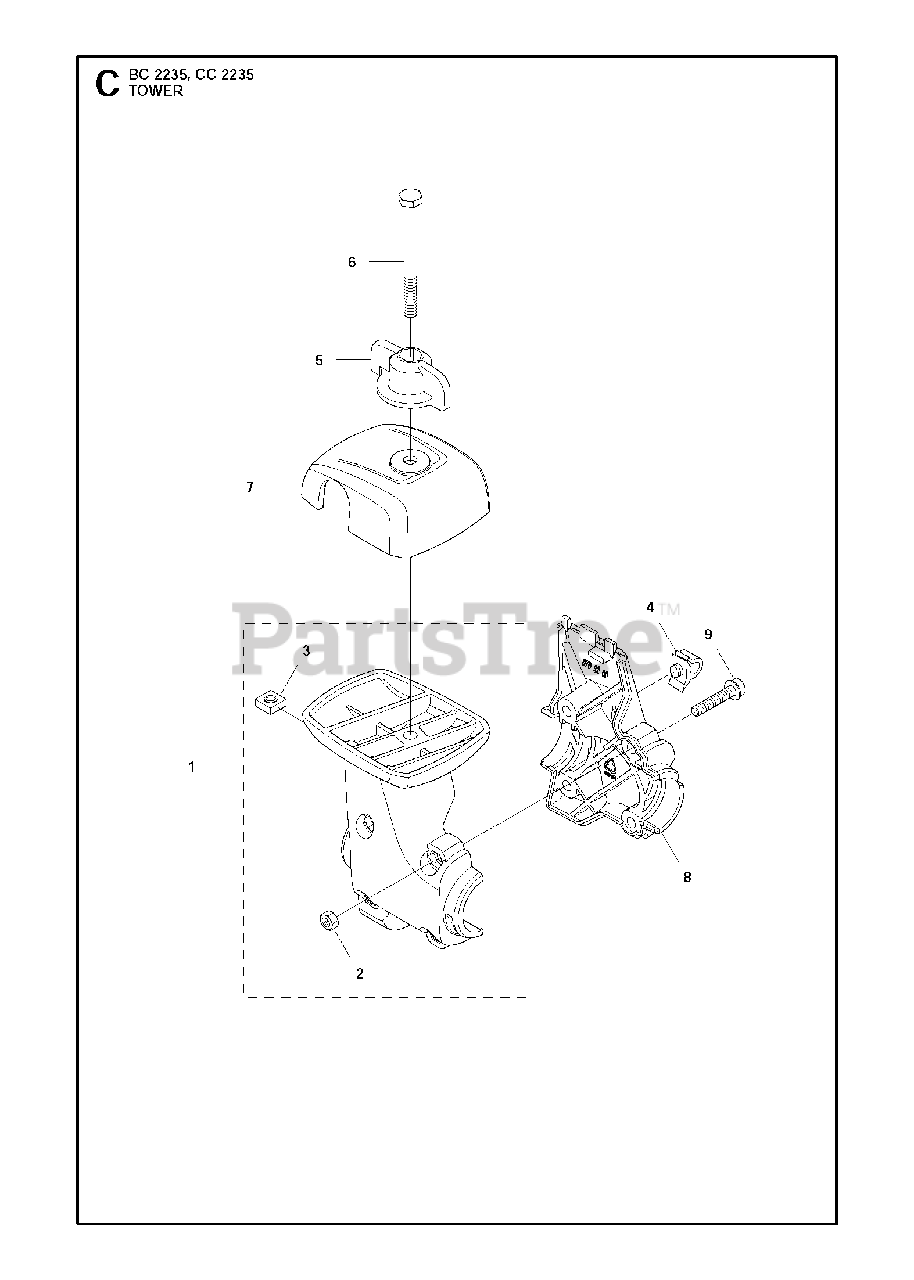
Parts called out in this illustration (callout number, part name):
2	NUT
3	NUT
6	SCREW EHHM
